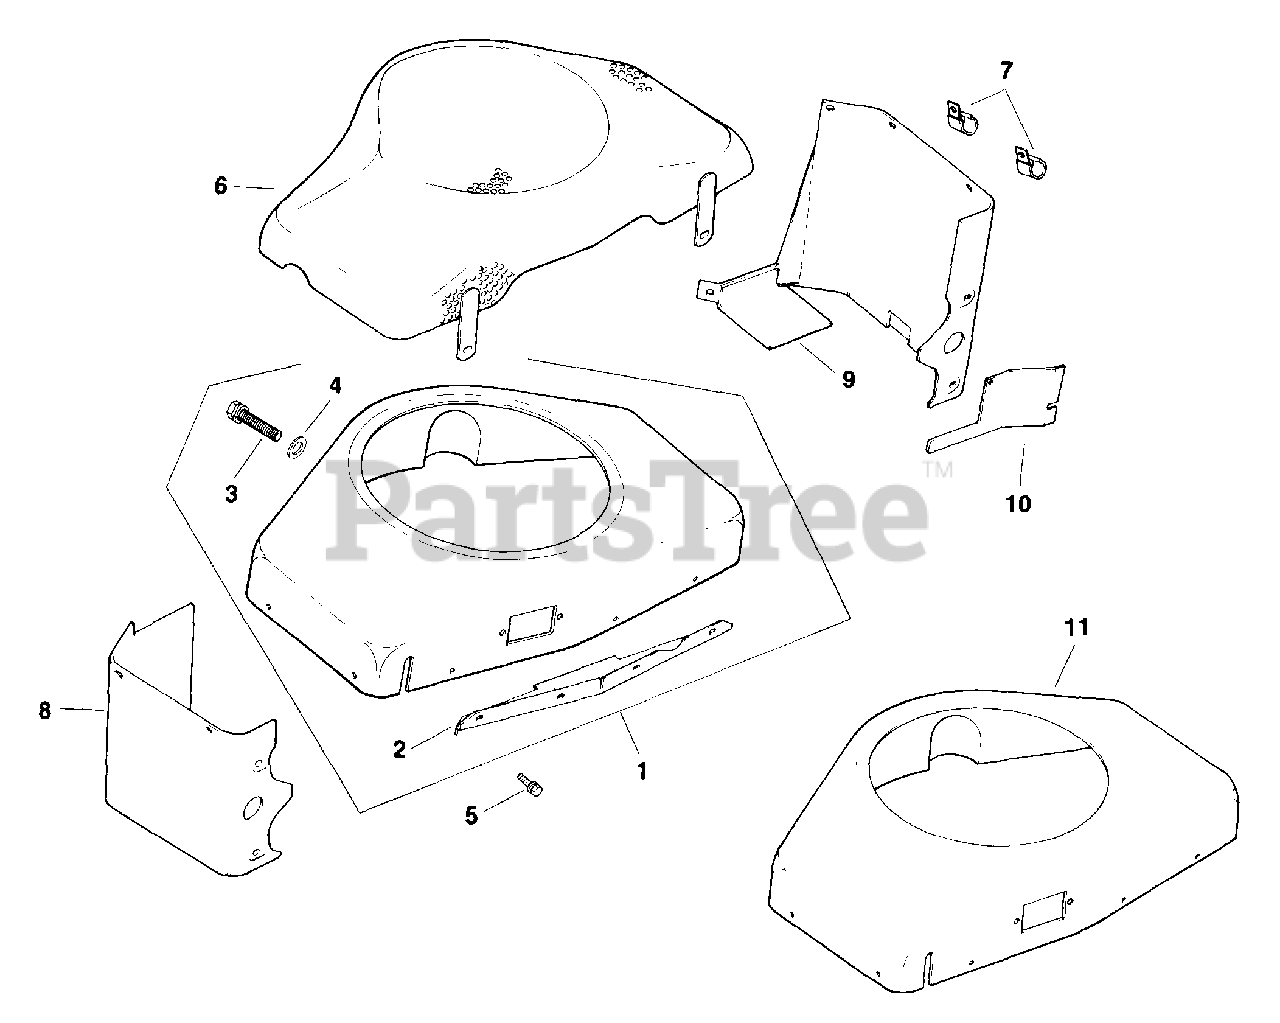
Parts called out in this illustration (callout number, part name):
1	KIT, BLOWER HOUSING - DISCONTINUED
2	SUPPORT - (#DSC)
3	SCREW, WSH HD TAP 1/4-20-5/8" - DISCONTINUED
4	WASHER, FLAT 5/16" - DISCONTINUED
5	SCREW, WSH HD TAP 1/4-20X7/16" USE 25 086 106-S
7	CLIP, CABLE
8	BAFFLE, CYLINDER HEAD - (#DSC)
8	BAFFLE - DISCONTINUED
10	BAFFLE, FUEL PUMP - (#DSC)
